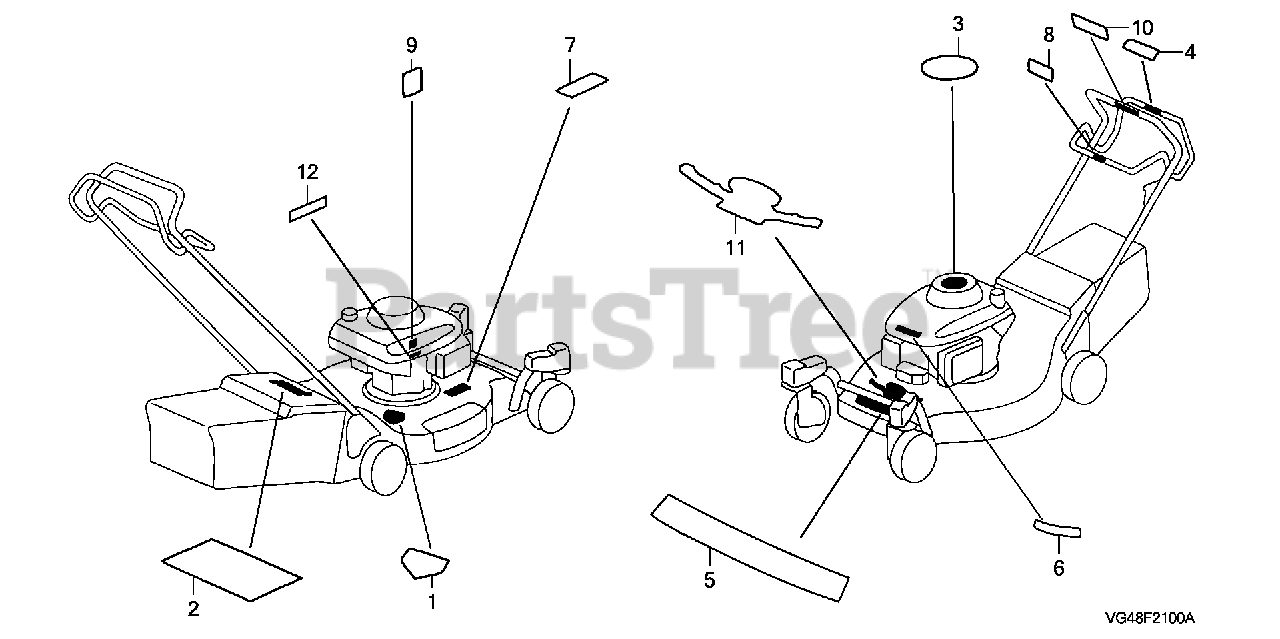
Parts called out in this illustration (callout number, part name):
1	CAUTION C, HOUSING
2	LABEL, WARNING (ENGLISH)
3	MARK, RECOIL COVER
4	MARK, CLUTCH INDICATION (ENGLISH)
5	MARK, HONDA
6	MARK, HONDA
7	LABEL, HEAT WARNING
8	MARK, BLADE CONTROL (ENGLISH)
9	MARK, OIL CAUTION
10	MARK, SALES POINT (ERGOACTIVE) (NOT AVAILABLE)
11	MARK, SALES POINT (HARMONY Z)
12	MARK, OIL RECOMMENDED
